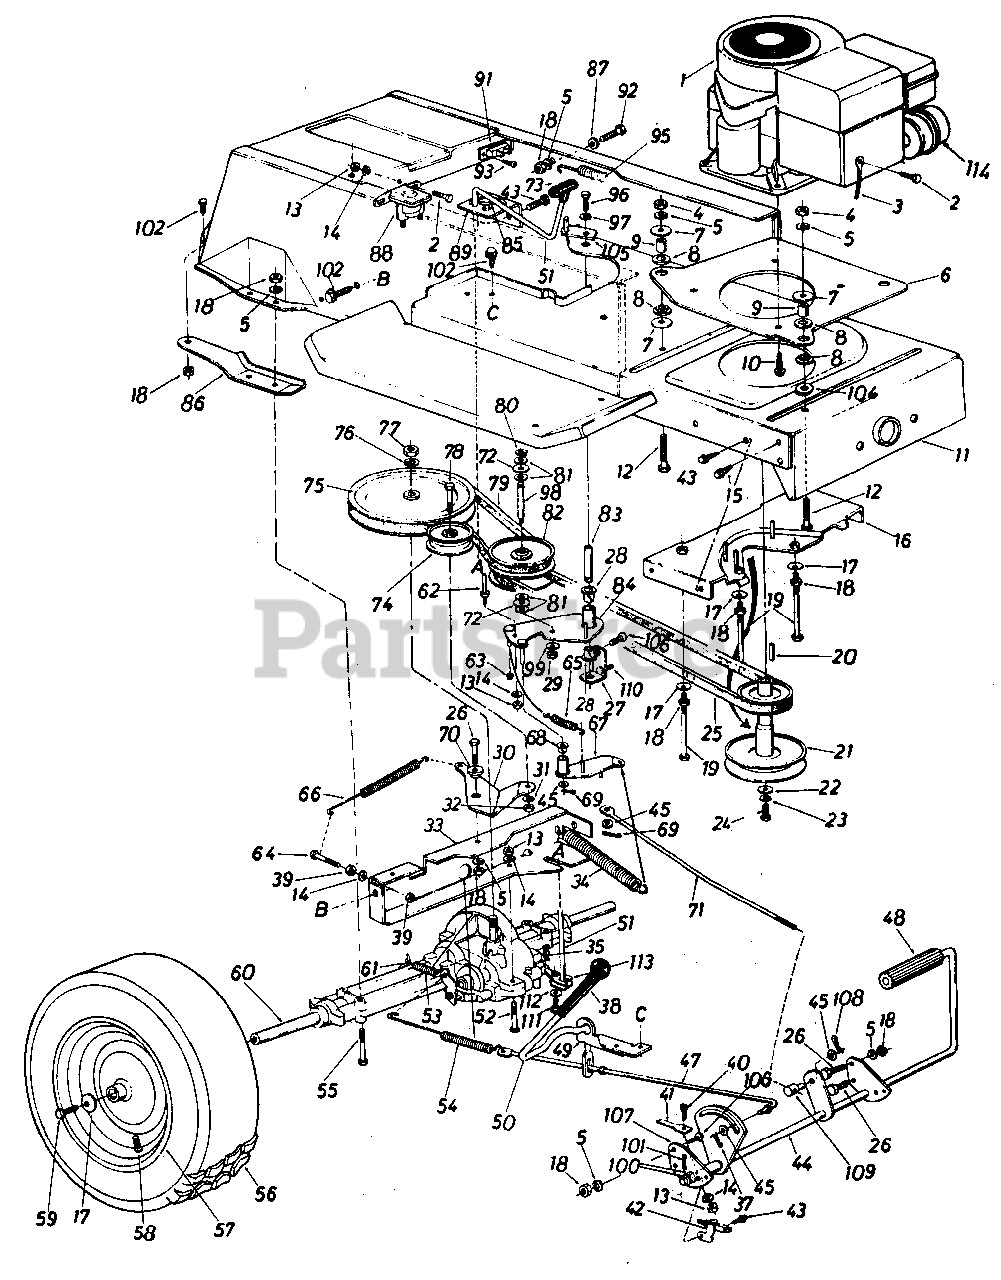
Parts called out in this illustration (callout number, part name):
1	Engine
2	Hex Bolt 1/4-20 x .62" Lg.
3	Electric Ground Wire
4	Hex Nut 5/16-24 Thd.
5	L-Wash. 5/16" I.D.
6	Engine Mounting Plate
7	Fl-Wash. .320" I.D. x 1.25"
8	Engine Mounting Grommet
9	Spacer
10	Hex Wash. Hd. TT-Tap Scr. 5/16-18 x 7/8" Lg.
11	Lower Frame Ass'y.
12	Hex Bolt 5/16-24 x 1.25"
13	Hex Nut 1/4-20 Thd.
14	L-Wash. 1/4" I.D.
15	Hex Wash. Hd. AB-Tap Scr. 5/16" x.75" Lg.
16	Belt Guard Brkt. Ass'y.
17	Bell-Wash. .345" I.D. x .88"
18	Hex Nut 5/16-18 Thd.
19	Hex Bolt 5/16-18 x 5.25" Lg.
20	Sq. Key 1/4" x 1/4" x 2.00"
21	Engine Pulley
22	Fl-Wash. 7/16" I.D. x 1.25"
23	L-Wash. 7/16" I.D.
24	Hex Bolt 7/16-20 x 1.50" Lg.
25	Variable-Speed Belt .715 x 53" Lg.
27	Bearing Shaft Bracket Ass'y.
28	Flanged Nyliner Brg. 5/8" I.D. x .88" Lg.
29	Hex Nut 3/8-24 Thd.
30	Idler Bracket
31	L-Wash. 3/8" I.D.
32	Hex Nut 3/8-24 Thd.
33	Transaxle Support Brkt.
34	Ext. Spring .94" O.D. x 6.7
35	Inter. Cott-Pin
37	Cotter Pin 3/32" Dia. x .75"
38	Grip Black
39	Hex Nut 1/4-28 Thd.
40	Hex Bolt 1/4-20 x 1.00" Lg.
41	Switch Actuator
42	Safety Switch
43	Hex Wash. Hd. S-Tap Scr. 1/4-20 x .50" Lg.
44	Clutch & Brake Pedal Ass'y.
45	Fl-Wash.
47	Brake Rod 20.9" Lg.
48	Foot Pad
49	Brake Lever Bracket
50	Hill Holder Brake Handle
51	Shift Lever Ass'y.
52	Hex Bolt 1/4-28 x 1.75" Lg.
53	Ext. Spring .38" O.D. x 2.5"
54	Ext. Spring .59" O.D. x 7.08'
55	Hex Bolt 5/16-18 x 2.75"
56	Wheel Ass'y. Comp.
57	Wheel Rim Only
58	Air Valve
59	Hex Bolt 5/16-24 x .75" Lg.
60	Transaxle Complete
61	Brake Return Spring Anchor
62	Belt Guard Pin 1/4-20 Thd.
63	Cap Speed Nut 1/4" Dia.
64	Hex Bolt 1/4-28 x 1.25" Lg.
65	Ext. Spring .50" Dia.
66	Ext. Spring .62" O.D. x 6.12"
67	Variable Speed Torque Brkt. Ass'y.
68	Flanged Bearing
69	Cotter Pin 3/32" Dia.
70	Shoulder Spacer .500" Dia. x.27" Lg.
71	Speed Control Link
72	Truss Bearing .56 Dia. x 1 .25"
73	Ball Knob
74	Fl-Idler Pulley 3.25" x 1.0"
75	1/2" 'V"-Pulley 8.0" O.D. x .501 " I.D.
76	L-Wash. 1/2" I.D.
77	Hex Jam Nut 1/2-20 Thd.
78	Hex Bolt 3/8-24 x .75" Lg.
79	Variable Speed Belt .715 x 44" Lg.
80	Snap Ring .56" Dia.
81	Fl-Wash.
82	Variable Speed Pulley Ass'y. 5" O.D.
83	Bearing Shaft
84	Variable Speed Brkt. Ass'y.
85	Comp. Spring Clip
86	Transaxle Support Brkt. R.H.
87	Fl-Wash. .34 I.D. x 1.12 O.D.
88	Solenoid
89	Shift Lever Bracket
91	Circuit Breaker
92	Hex Bolt 5/16-18 x 1.50" Lg.
93	Truss Hd. Phil. Scr. #10 x 1/2 " Lg .
95	Ext. Spring .99" O.D. x 11.0"
96	Hex Bolt 3/8-24 x .75" Lg.
97	Bell-Wash. .38" I.D. x .88"
98	Shaft .56" Dia. x 3.875" Lg.
99	Bell-Wash. .39" I.D. x 1.12"
100	Fl-Wash.
101	Cotter Pin 3/32" Dia. x 1.0"
102	Hex Wash. Hd. Scr. 5/16-18 x.62" Lg.
104	Fl-Wash. .32" I.D. x 1.25"
105	Belt Guard
106	Truss Mach. Scr. 5/16-18 x .75" Lg.
107	Pedal Bracket
108	Cotter Pin 3/32" Dia. x .75"
109	Ferrule
110	Truss Phillips Hd. Sc:. 5/16-18 x 1.0" Lg.
111	Hex Bolt 1/4-28 x .50" Lg.
112	Bell-Wash. .265" I.D. x .75"
113	Shift Lever Link Ass'y.
